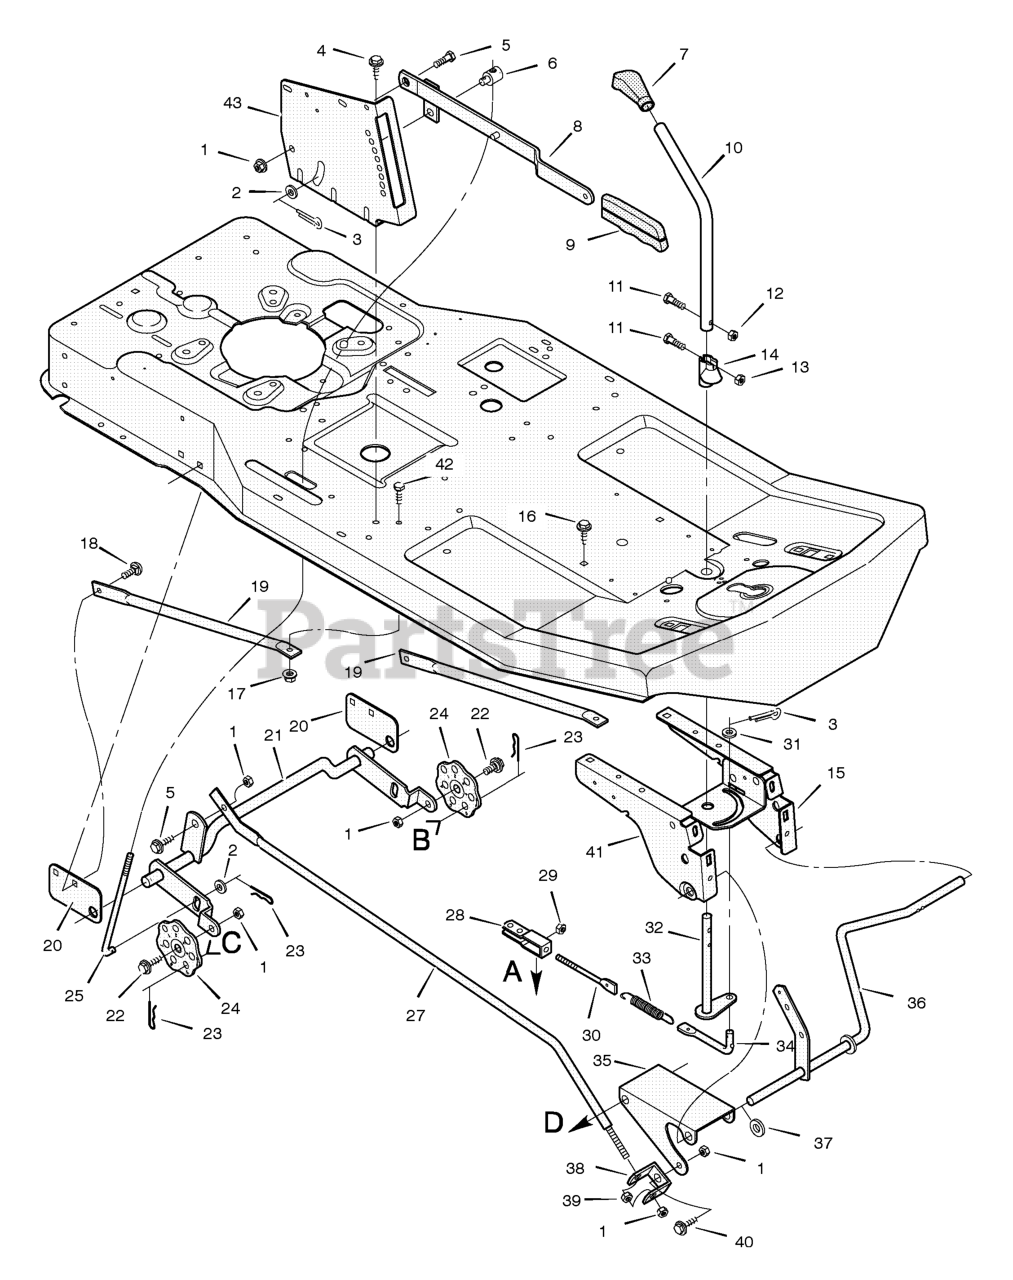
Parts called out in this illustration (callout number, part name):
1	Locknut, Flange
2	Washer
3	Pin, Cotter
5	Bolt, Shoulder
6	Nut, Adjusting
7	Grip, Blade Control
8	Lever Assembly, Lift
9	Grip, Lift Lever
10	Attachment, Clutch
11	Bolt, Hex
12	Locknut
13	Locknut, Flange
14	Cam, Blade Control
15	Plate, Left Suspension
17	Locknut, Flange
18	Bolt, Carriage
19	Strut, Frame
20	Plate, Mounting
21	Rod Assembly, Rear Suspension
22	Bolt, Shoulder
23	Pin, Hair
24	Plate, Adjusting
25	Rod, Lifter
27	Rod, Suspension
29	Nut, Hex
30	Link, Blade Drive
32	Rod and Arm Assembly
33	Spring, Extension
34	Link, Front Deck
35	Bracket, Front Suspension
36	Lever, Pedal
37	Washer
38	Clevis
39	Locknut, Hex
40	Bolt, Shoulder
41	Plate, Right Suspension
42	Bolt, Hex
43	Plate, Index
